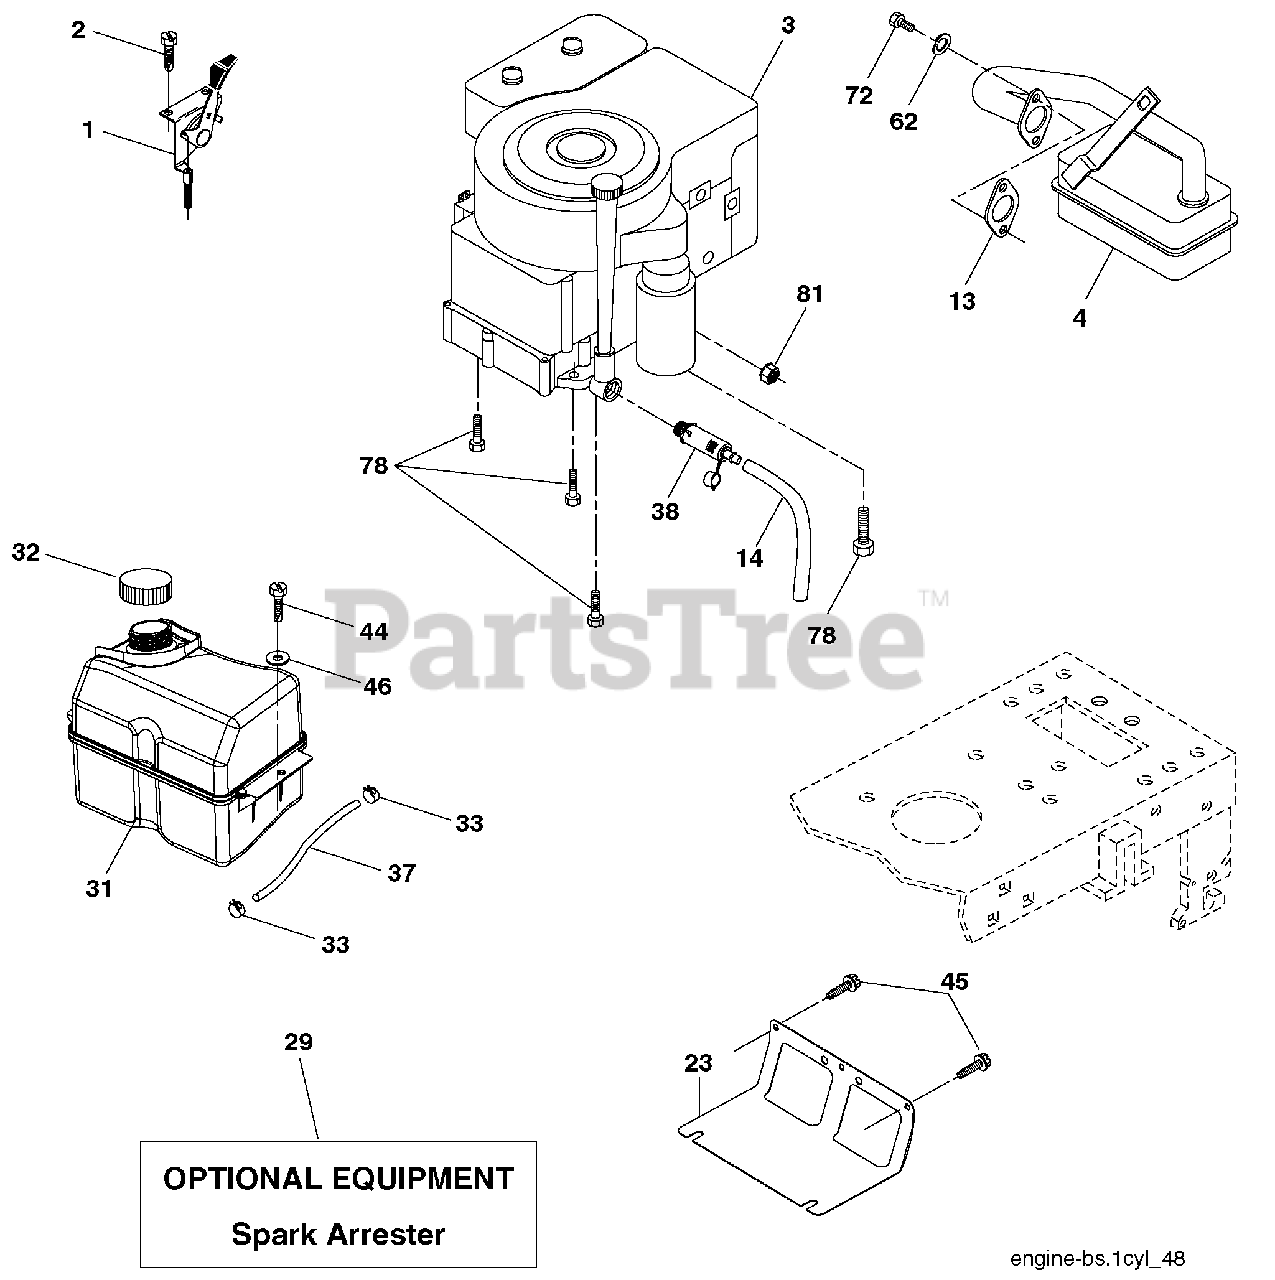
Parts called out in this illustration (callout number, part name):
1	Control, Throttle
2	Screw Hex Thd Cut 1/4-20 x 1/2
4	Muffler
13	Muffler Gasket
14	Tube Oil Drain
23	Shield, Browning/Debris Guard
29	Arrester, Spark
31	Tank, Fuel
32	Cap, Fuel
33	Clamp, Hose Blk
37	Line, Fuel
38	Plug Drain Oileasy
44	Screw Hex Wsh Thdrol 1/4-20 x 3/4
45	Screw Hex Wsh Thdrol 3/8-16 x 3/4
46	Washer 9/32 x 7/8 x 16 Ga.
62	Washer Split
72	Screw Socket Hd 5/16-18 x .75
78	Screw 3/8-16 x 1-1/4
81	Nut Keps Hex 1/4-20 unc
